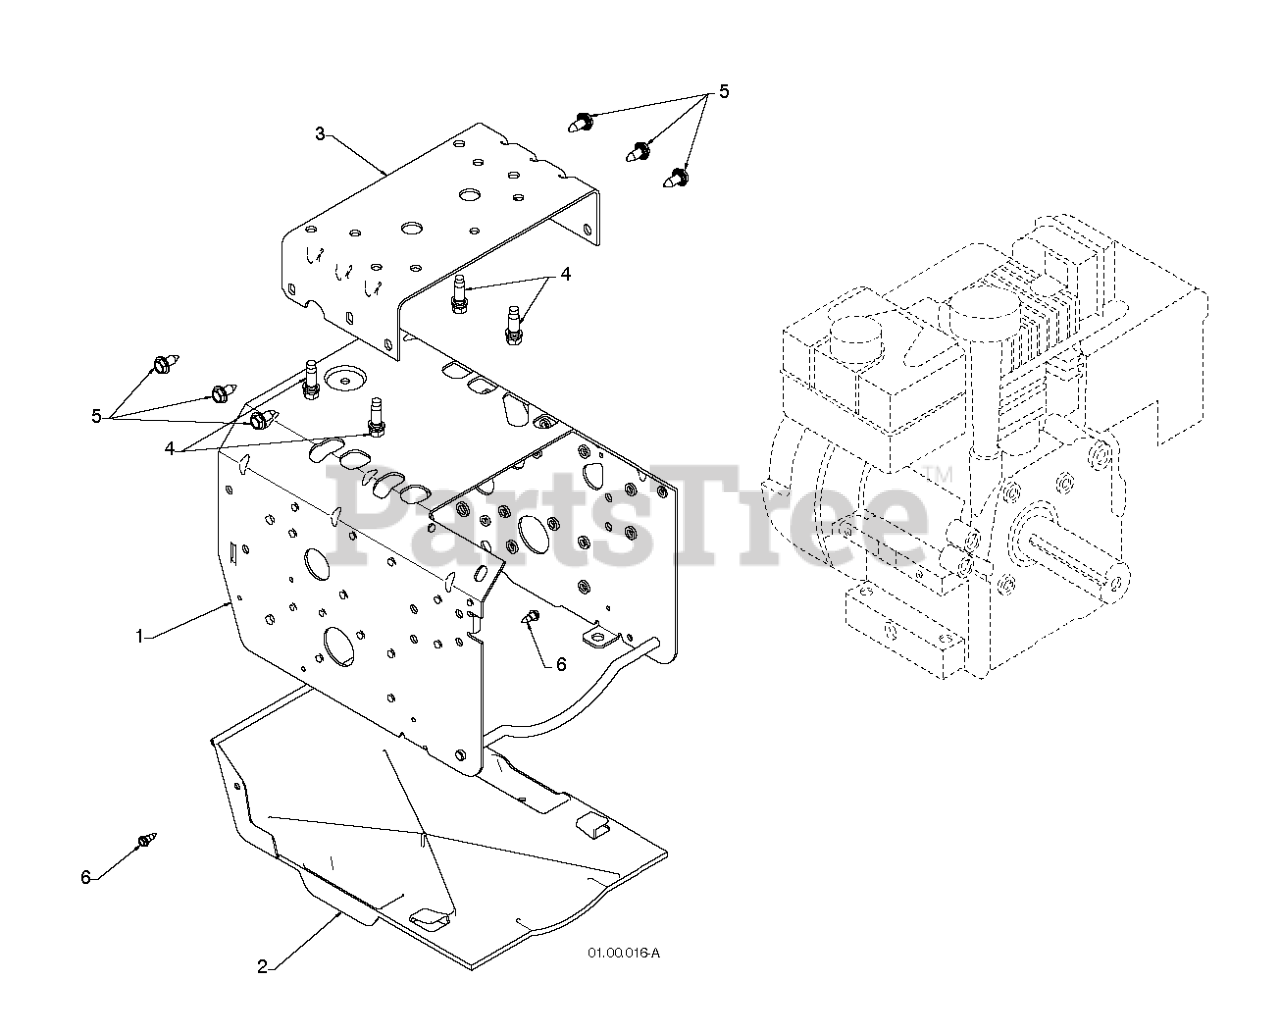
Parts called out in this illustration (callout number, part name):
1	FRAME.WELD.PNT.003BGP
2	PAN.BOTTOM.PLASTIC
3	PLATE.ENGINE.MOUNT.PNT
4	BOLT 3/8-16X1-1/8
5	SELF-TAPPING SCREW 5/16-18X3/4
6	SCREW, HEX HEAD, TAPPING
